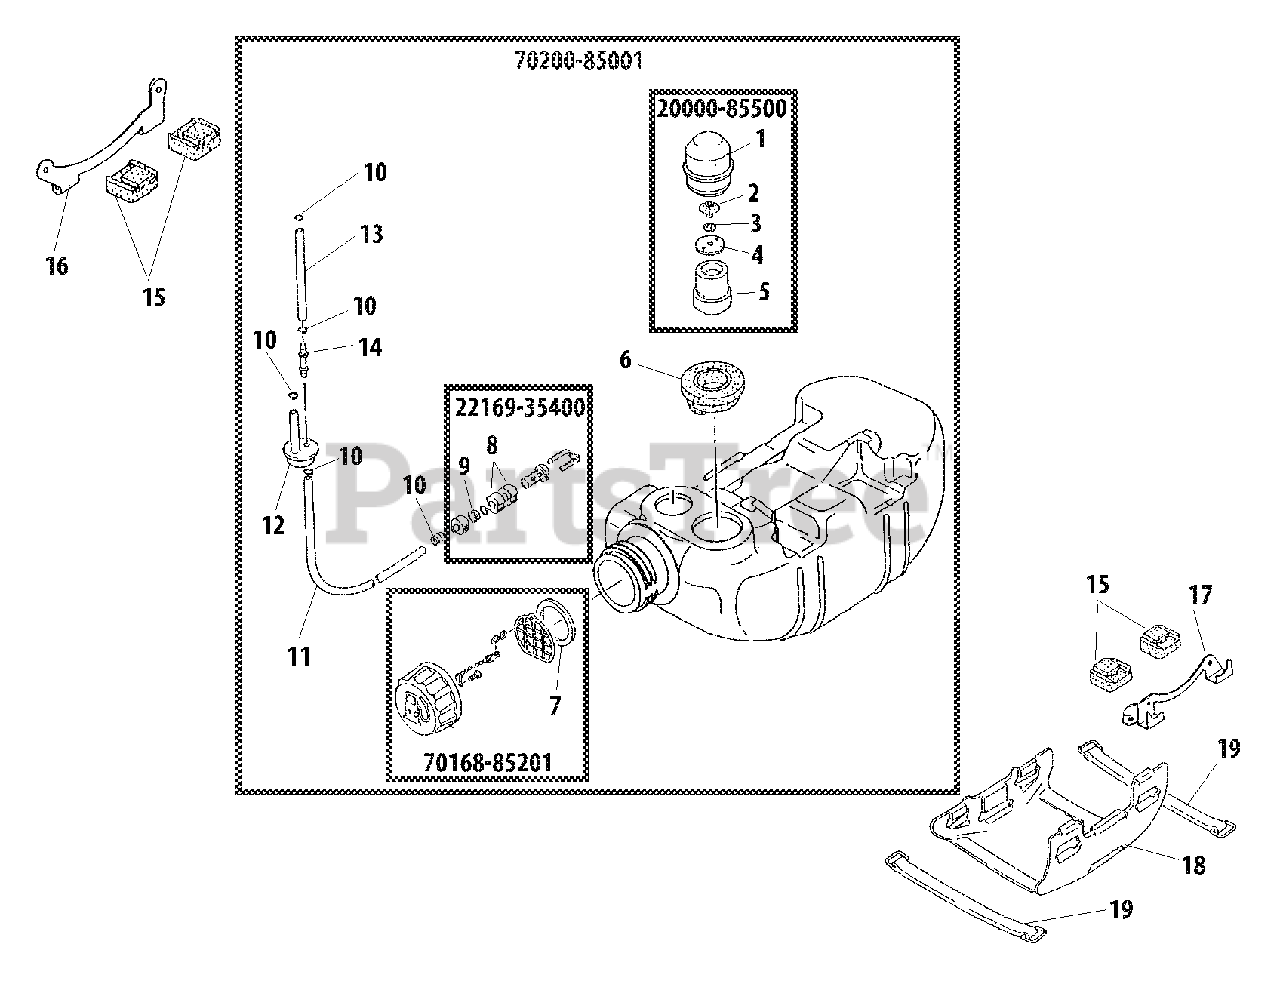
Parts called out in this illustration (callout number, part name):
1	CAP, BREATHER
2	VALVE, BREATHER
3	WASHER
4	RETAINER
5	HOLDER, VENT
6	GROMMET
7	GASKET, CAP
8	FILTER, FUEL
9	SCREEN, FILTER
10	RING, RETAINING - 6
11	PIPE - FUEL
12	GROMMET
13	PIPE - FUEL
14	JOINT
15	CUSHION
16	BRACKET - INNER
17	BRACKET - OUTER
18	GUARD, FUEL TANK
19	STRAP, FUEL TANK
20000-85500	VENT, FUEL TANK
22169-35400	FUEL FILTER ASSY
70168-85201	CAP ASSY
70200-85001	FUEL TANK ASSY
